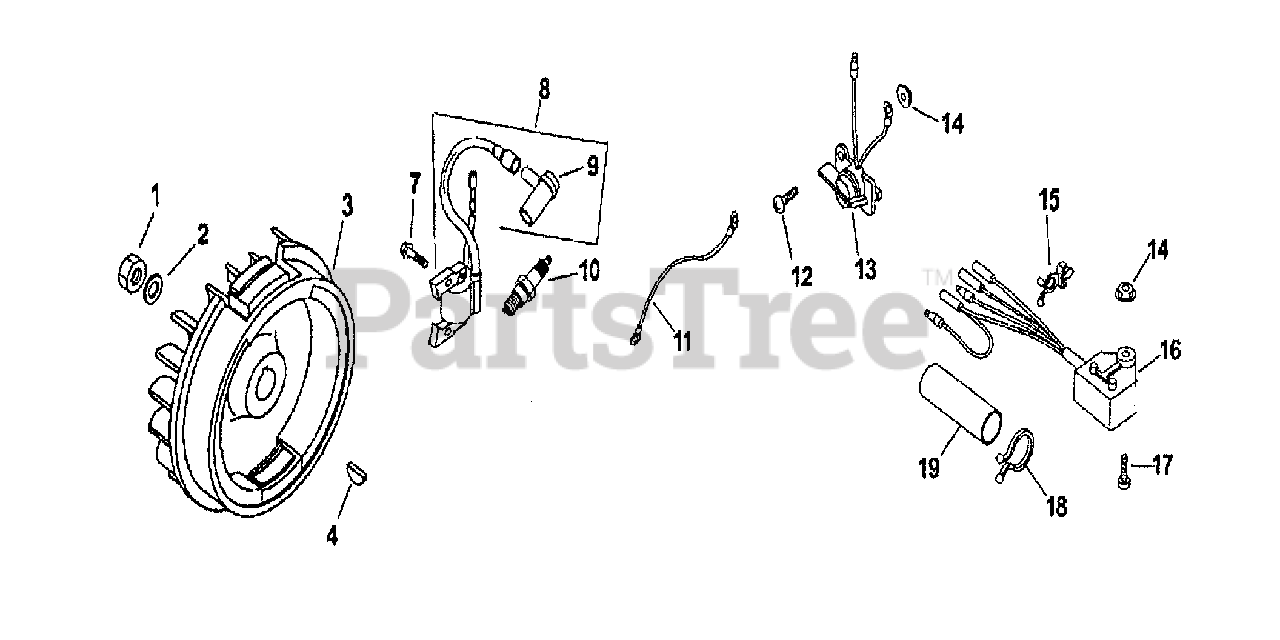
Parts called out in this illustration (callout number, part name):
1	Nut, Flywheel
2	Washer, Flywheel
4	Key, Flywheel
8	Ignition Module
9	Cap, Spark Plug
10	Plug, Spark
11	Ground, Ignition
12	Screw, Stop Switch
19	Sleeve, Wiring
